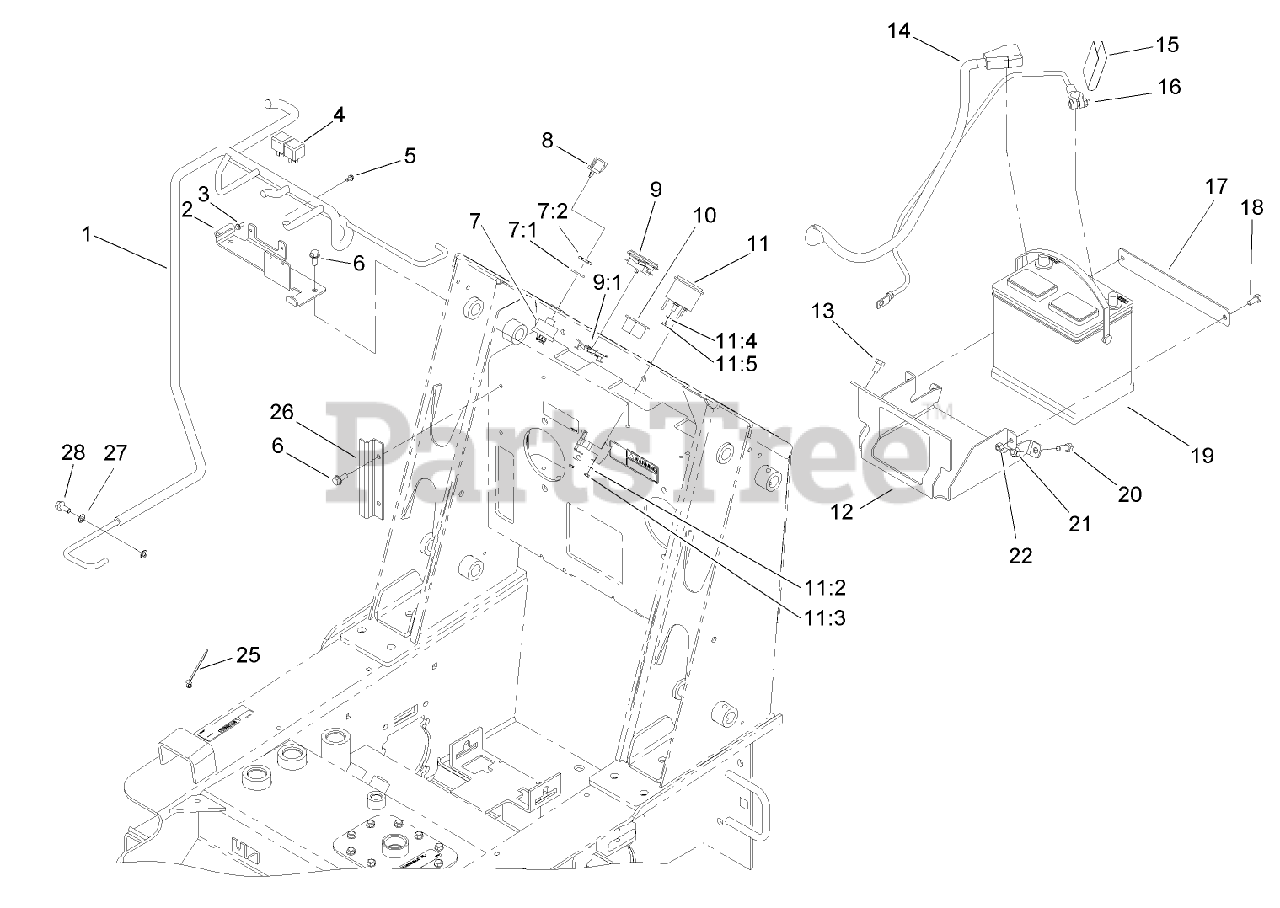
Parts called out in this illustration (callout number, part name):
1	HARNESS-WIRE
2	Fuse/Relay Bracket ASM
3	SCREW-HWH
4	RELAY
5	SCREW-HWH
6	SCREW-HWHTF
7	Key Switch ASM
7:1	WASHER-TOOTH, INTERNAL
7:2	NUT-HH
8	KEY-IGNITION
9	INDUCTIVE HOURMETER ASM
9:1	CLIP-MOUNTING
10	PLUG-HOLE
11	GAUGE-FUEL
11:2	WASHER-LOCK, INT
11:3	NUT-HEX
11:4	WASHER-LOCK / EXT
11:5	NUT-HEX
12	TRAY-MOUNTING, BATTERY
13	SCREW-HWHTF
14	CABLE-BATTERY, POSITIVE
15	DECAL-INSTRUCTIONS, CHARGING
16	CABLE-BATTERY, NEGATIVE
17	CLAMP-BATTERY
18	SCREW-HH
19	BATTERY
20	SCREW-HH
21	NUT-LOCK, NI
22	NUT-LOCK, NI
25	TIE-CABLE
26	SHIELD-WIRING
27	WASHER-LOCK
28	SCREW-HHF
